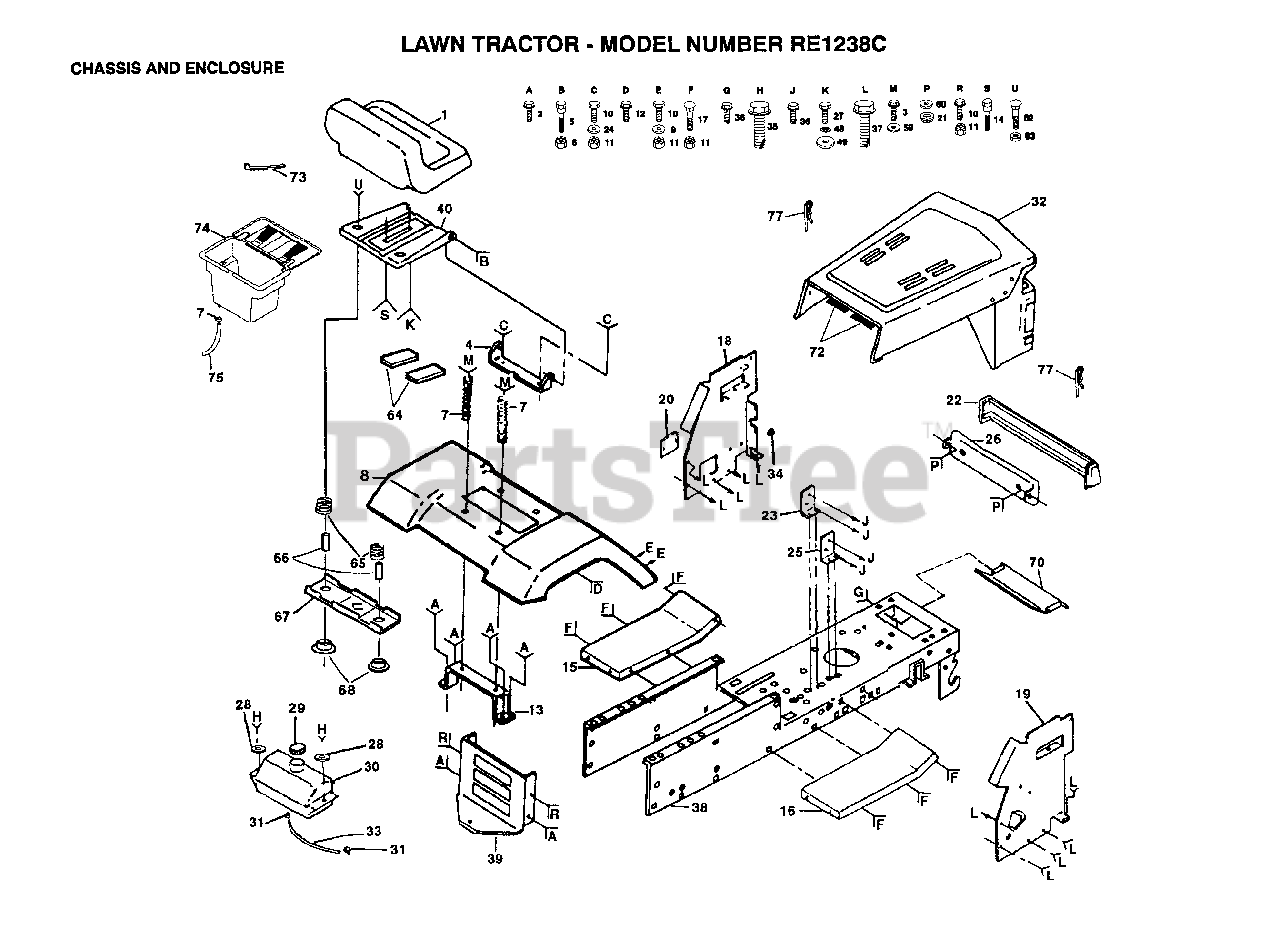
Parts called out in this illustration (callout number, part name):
2	SCREW
3	SCREW GTV
7	SPRING COMPRESSIO
9	WASHER
12	SCREW LT
14	"BOLT,SHOULDER"
15	FOOTREST LH
16	FOOTREST
17	BOLT
18	PANEL DASH LH
20	COVER ACCESS
21	PAL NUT LT
23	SWITCH BRACKET
24	WASHER
25	BRACKET LT
27	BOLT
28	WASHER GT
30	TANK.FUEL.LT.
31	HOSE CLAMP
32	HOOD&GRILL ASSY
33	FUEL LINE T
34	SNAP BUSHING T
35	SCREW
36	SCREW
37	SCREW LT
38	CHASSIS WELDMENT
39	DRAWBAR LT/YT
48	LOCKWASHER
49	WASHER
59	WASHER
60	WASHER PM
62	BOLT
64	STRIP FORM
65	SPRING
66	SPACER SPLIT
67	BRKT SWITCH
68	BUSHING
70	HEAT SHIELD
76	HOSE CLAMP T
77	SPRING.RETAINER
